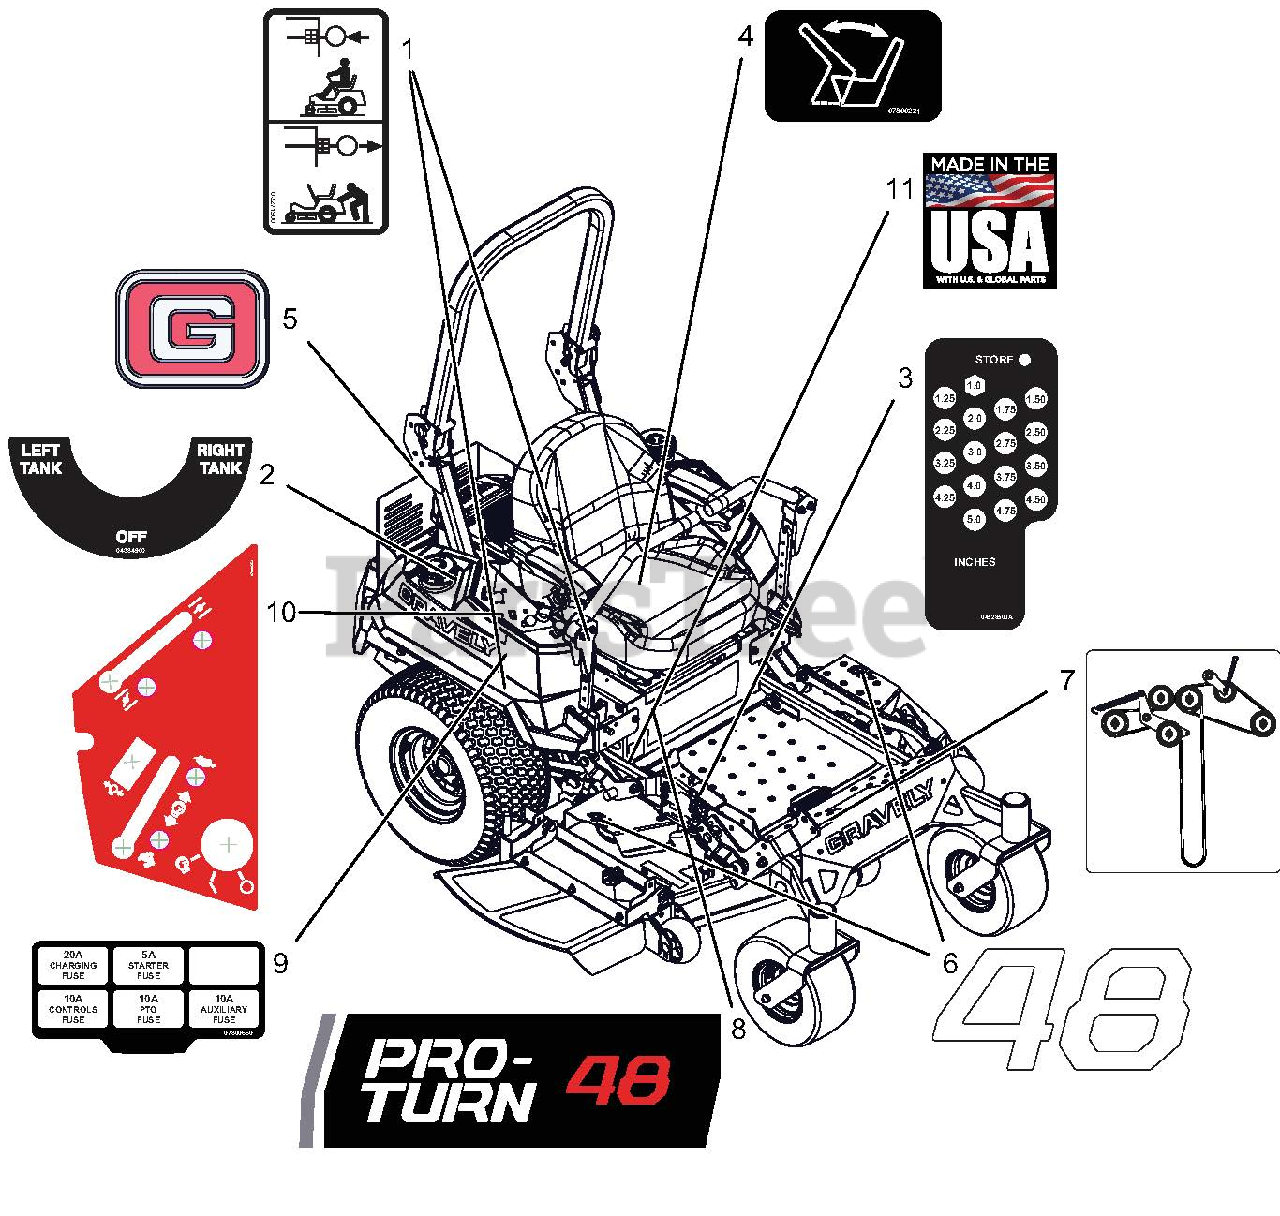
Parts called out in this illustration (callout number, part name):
1	DECAL, TRANSMISSION DISCONNECT
2	DECAL, FUEL VALVE
3	DECAL, HEIGHT OF CUT
4	DECAL - SEAT RELEASE
5	DECAL, GRAVELY BRAND
6	DECAL, 48"
7	DCL,BELT ROUTE-RH V-SIDE IDLER
8	DECAL, PRO-TURN 48
9	DECAL, FUSE BLOCK
10	DECAL, NON-EFI CONTROL PANEL
11	DECAL, MADE IN USA
